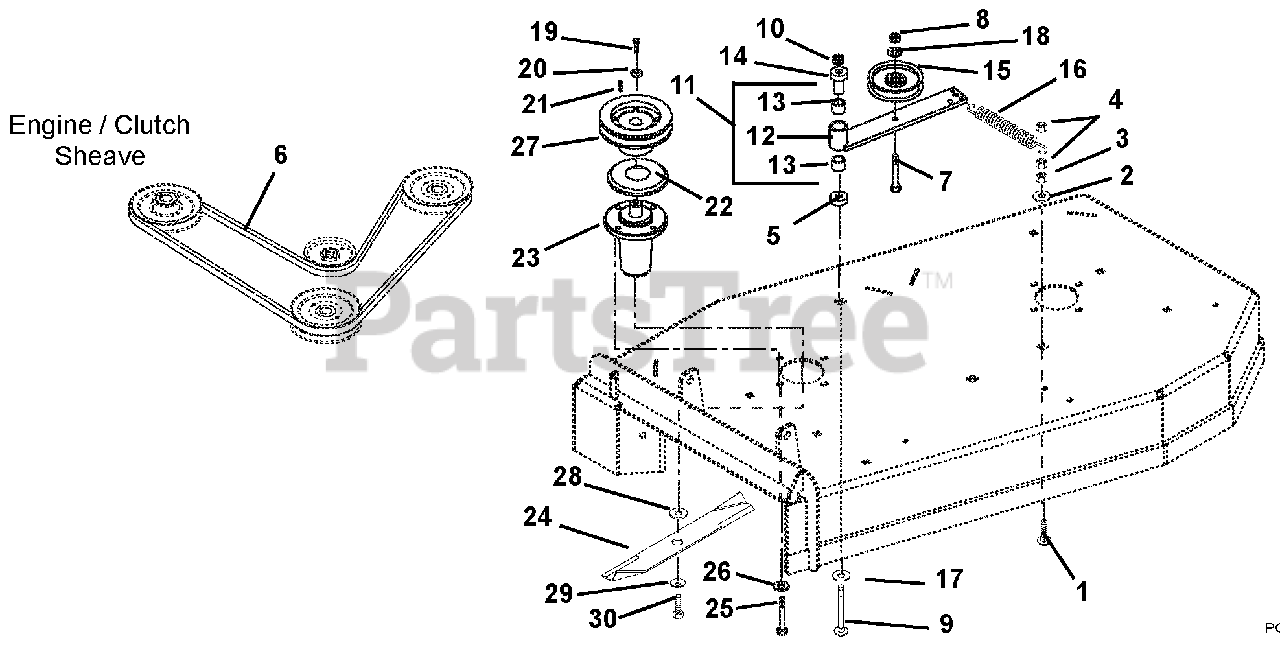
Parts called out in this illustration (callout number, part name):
1	Bolt-Round Head Square Neck .38-16 x 1.50 Grade 5
2	Washer-Locking .38 x .094 Regular
3	Nut-Hex .38-16
4	Nut-Locking-Center .38-16
5	Washer-Flat-Steel .515 x 1.625 x .25
6	V-Belt B-Section 36.70 x .650
7	Bolt-Round Head Square Neck .38-16 x 3.00 Grade 5
8	Nut-Locking-Center .38-16
9	Bolt-Round Head Square Neck .50-13 x 3.75 Grade 5
10	Nut-Locking-Center .50-13
11	Assembly, Idler Pivot Arm (Contains Items 12 & 13)
12	Weldment, Idler Pivot Arm
13	Bearing, 1.00 x 1.12 x .75
14	Bearing, Pedestal Powdered Metal
15	Idler-Flat 4.00 x .38 (2.00 W)
16	Spring, Extension
17	Washer-Flat-Steel .755 x 1.375 x .062
18	Seal, Idler Bearing
19	Bolt-Hex .38-16 x 1.00 Grade 8
20	Washer-Cupped-Serrated .375
21	Key, Square .25 x .25 x 1.00 RC 40-50
22	Slinger-Dust
23	Assembly, Maintenance Free Spindle
24	Blade- Mower
25	Bolt-Hex .38-16 x 1.00 Grade 5
26	Washer-Locking .38 x .094 Regular
27	Pulley
28	Washer, Flat .64 x 1.81 x .250
29	Washer-Bellville .63 x 1.625 x .14
30	Bolt-Hex .62-18 x 1.75 Grade 8
